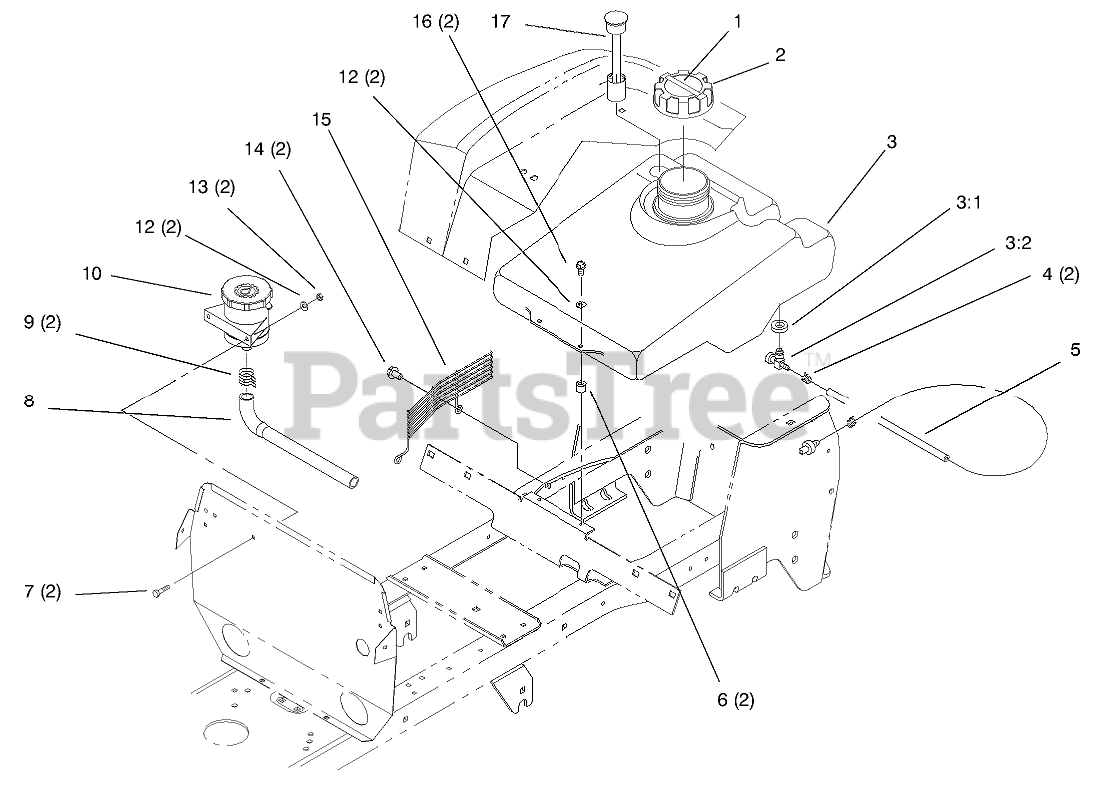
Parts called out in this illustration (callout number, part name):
2	GAS CAP ASM
3	TANK-GAS
3:1	BUSHING
3:2	VALVE-FUEL
4	CLAMP-HOSE
5	HOSE - FUEL LINE TWIN
6	SPACER - FUEL TANK
7	SCREW-HH
8	HOSE - HYDRO
9	CLAMP-HOSE
10	ASS'Y-RESERVOIR
12	WASHER-FLAT
13	NUT-LOCK, NI
14	Screw-HWH (Only On: 72104)
15	Guard-Fan (Only On: 72104)
16	SCREW-HH
